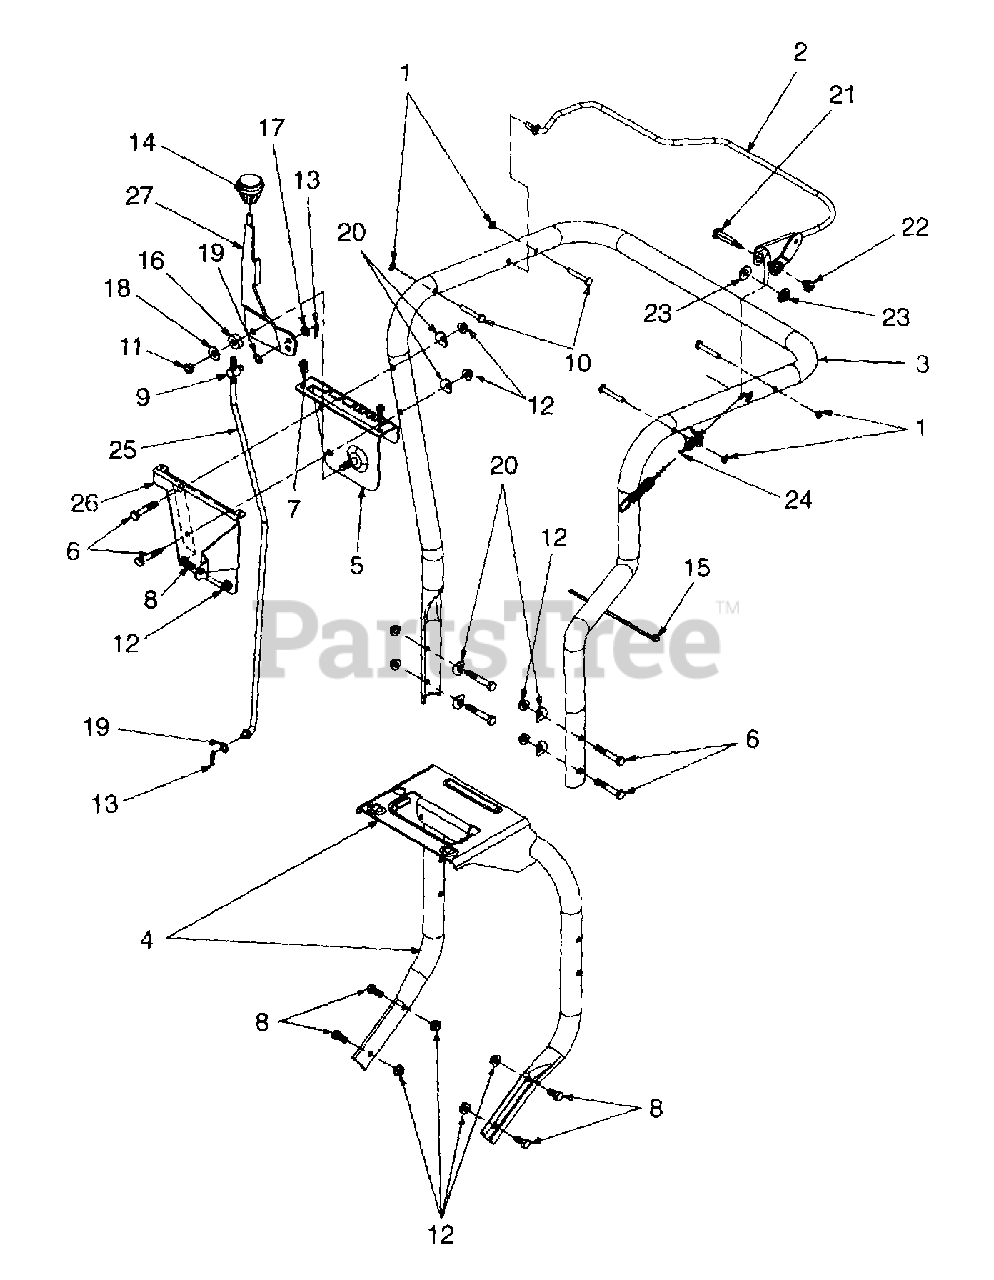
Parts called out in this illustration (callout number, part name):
1	Nut, Push, .25
2	Control Assembly, Clutch
3	Handle Assembly, Upper
4	Handle Assembly, Lower
5	Bracket Assembly, Shift
6	Screw, Hex Cap, 5/16-18 x 2.0
7	Screw,Hex Wash Hd, 4-14x
8	Screw, Hex Cap 5/16-18 x .75
9	Ferrule
10	Pin, Stud, .250 x 1.75
11	Nut, Hex Insert Jam Lock 3/8
12	Nut, Hex Flange Lock 5/16-18
13	Pin, Internal Cotter
14	Knob, Shift
15	Cable Tie
16	Washer, Rubber
17	Washer, Flat, .385 x .62 x .06
18	Washer, Flat, .406 x .875 x .059
19	Washer, Spring, .390 x .62
20	Washer, Saddle, .320 x .93
21	Shoulder Screw, .374 x 1.375
22	Shoulder Nut, 1/4-20
23	Bearing, Hex Plastic Flange
24	Cable, Clutch
25	Rod, Shift
